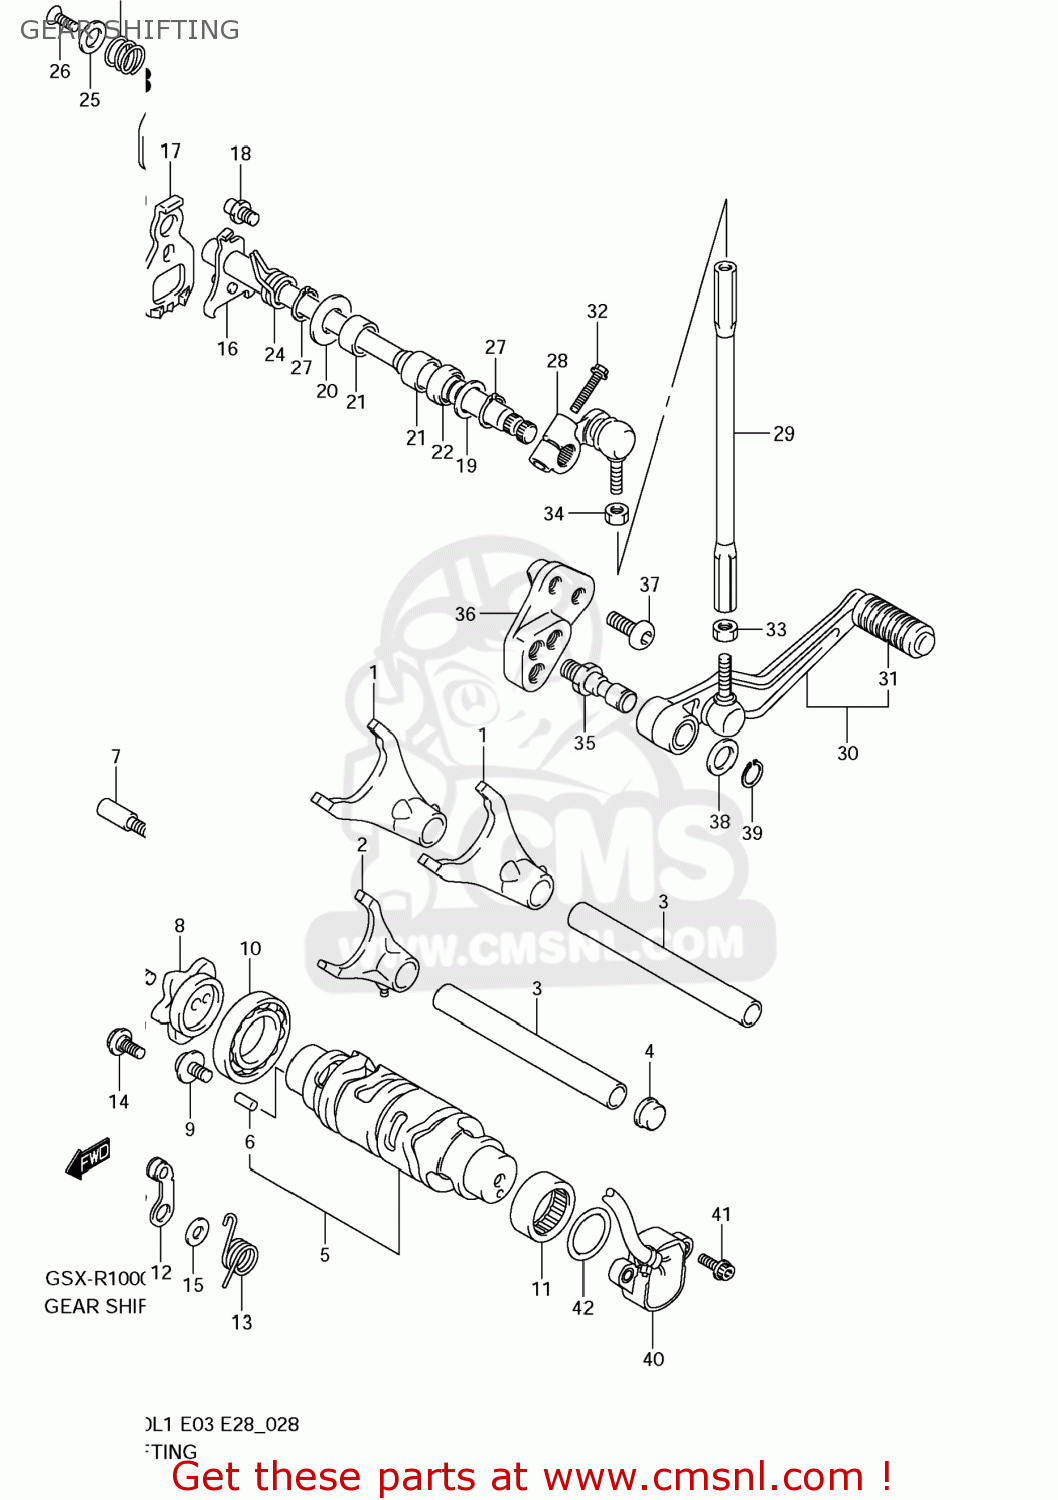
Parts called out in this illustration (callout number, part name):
1	FORK,GEAR SHIFT NO.1
2	FORK,GEAR SHIFT NO.3
3	SHAFT,GEAR SHIFT FORK(L:128)
4	PLUG,GEAR SHIFT FORK SHAFT
5	CAM,GEAR SHIFT
6	PIN
7	BOLT,GEAR SHIFT CAM PLATE
8	PLATE,GEAR SHIFT CAM
9	SCREW(6X12)
10	BEARING(25X47X8)
11	BEARING(25X32X12)
12	STOPPER,SHIFT CAM
13	SPRING,GEAR SHIFT CAM STOPPER
14	BOLT(6X14.3)
15	WASHER
16	SHAFT,GEAR SHIFT
17	PLATE,GEAR SHIFT CAM DRIVE
18	STOPPER,GEAR SHIFT ARM
19	WASHER(14X29X0.8)
20	SHIM(14X24X1)
21	BEARING(14X20X12)
22	SEAL,OIL(14X22X7.3)
23	SPRING,GEAR SHIFT PLATE RETURN
24	SPRING
25	WASHER,GEAR SHIFT SHAFT END
26	SCREW(6X16)
27	CIRCLIP
28	ARM,GEAR SHIFT LINK
29	ROD,GEAR SHIFT LINK
30	LEVER ASSY,GEAR SHIFT
31	RUBBER,GEAR SHIFT PEDAL
32	BOLT
33	NUT
34	NUT
35	SHAFT,GEAR SHIFT LEVER
36	BRACKET,GEAR SHIFT LEVER
37	BOLT(8X20)
38	WASHER(12.5X20X1)
39	CIRCLIP
40	SENSOR ASSY,GE
41	BOLT(5X16)
42	O RING(D:2.4,ID:26.2)
